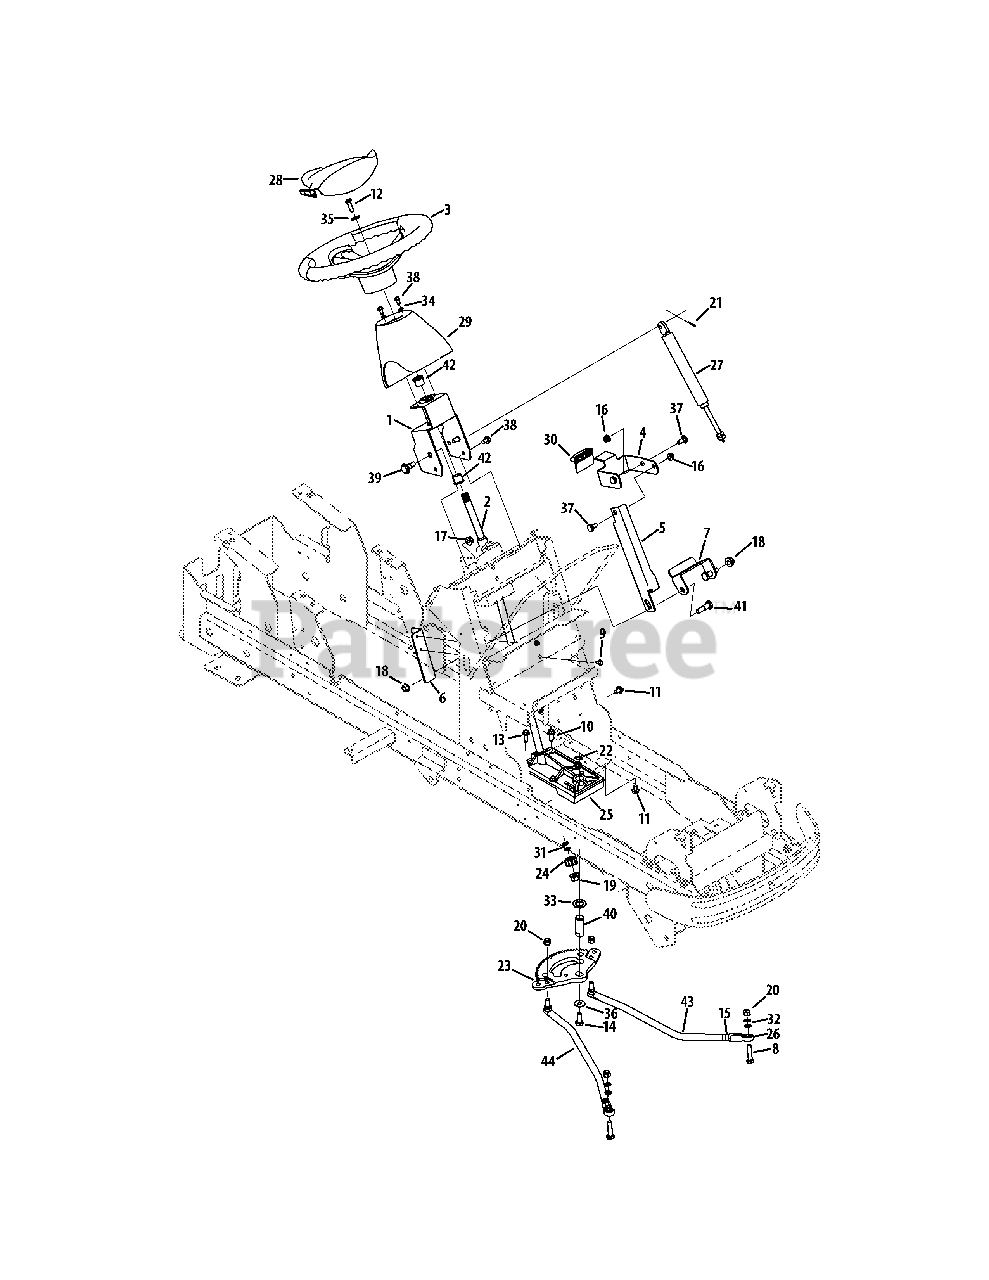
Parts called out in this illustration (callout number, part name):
1	Steering Upper Support Bracket
2	Manual Steering Assembly
3	Steering Wheel
4	Tilt Steering Lever Bracket
5	Tilt Steering Bracket
6	Tilt Steering Mount Bracket
7	Tilt Steering Pivot Bracket
8	Hex Screw, 3/8-24 x 1.75
9	Hex Washer Screw, 1/4-20 x .500
10	Hex Washer Screw, 5/16-18 x 1.000
11	Hex Washer Screw, 5/16-18 x .625
12	Hex Lock Screw, 5/16-18 x 1.00
13	Hex Washer Screw, 5/16-18 x 1.250
14	Hex Screw, 5/16-18 x .75
15	Jam Nut, 7/16-20
16	Flange Lock Nut, 5/16-18
17	Flange Lock Nut, 3/8-16
18	Flange Lock Nut, 3/8-16
19	Flange Lock Nut, 7/16-20
20	Hex Lock Nut, 3/8-24
21	Cotter Pin, 3/32 x .750
22	Snap Ring, .750
23	Segment Gear
24	Pinion Gear
25	Steering Housing
26	End Rod, 7/16-20 x 3/8
27	Locking Damper Cylinder
28	Steering Wheel Cover
29	Dash Collar
30	Tilt Lever
31	Flat Washer, .510 x .750 x .033
32	Flat Washer, .385 x .62 x .063
33	Flat Washer, .76 x 1.49 x .06
34	Flat Washer, .344 x .62 x .033
35	Bell Washer, .340 x .872 x .060
36	Flat Washer, .344 x 1.00 x .063
37	Shoulder Screw, .435 x .178-5/16 x .56
38	Shoulder Screw, 1/4-20 x 0.500
39	Shoulder Bolt, 3/8-16 x .49 x .33
40	Steering Shaft
41	Shoulder Screw, 3/8-16 x .50 x .66
42	Flange Bearing, .630
43	LH Drag Link, 5/8
44	RH Drag Link, 5/8
